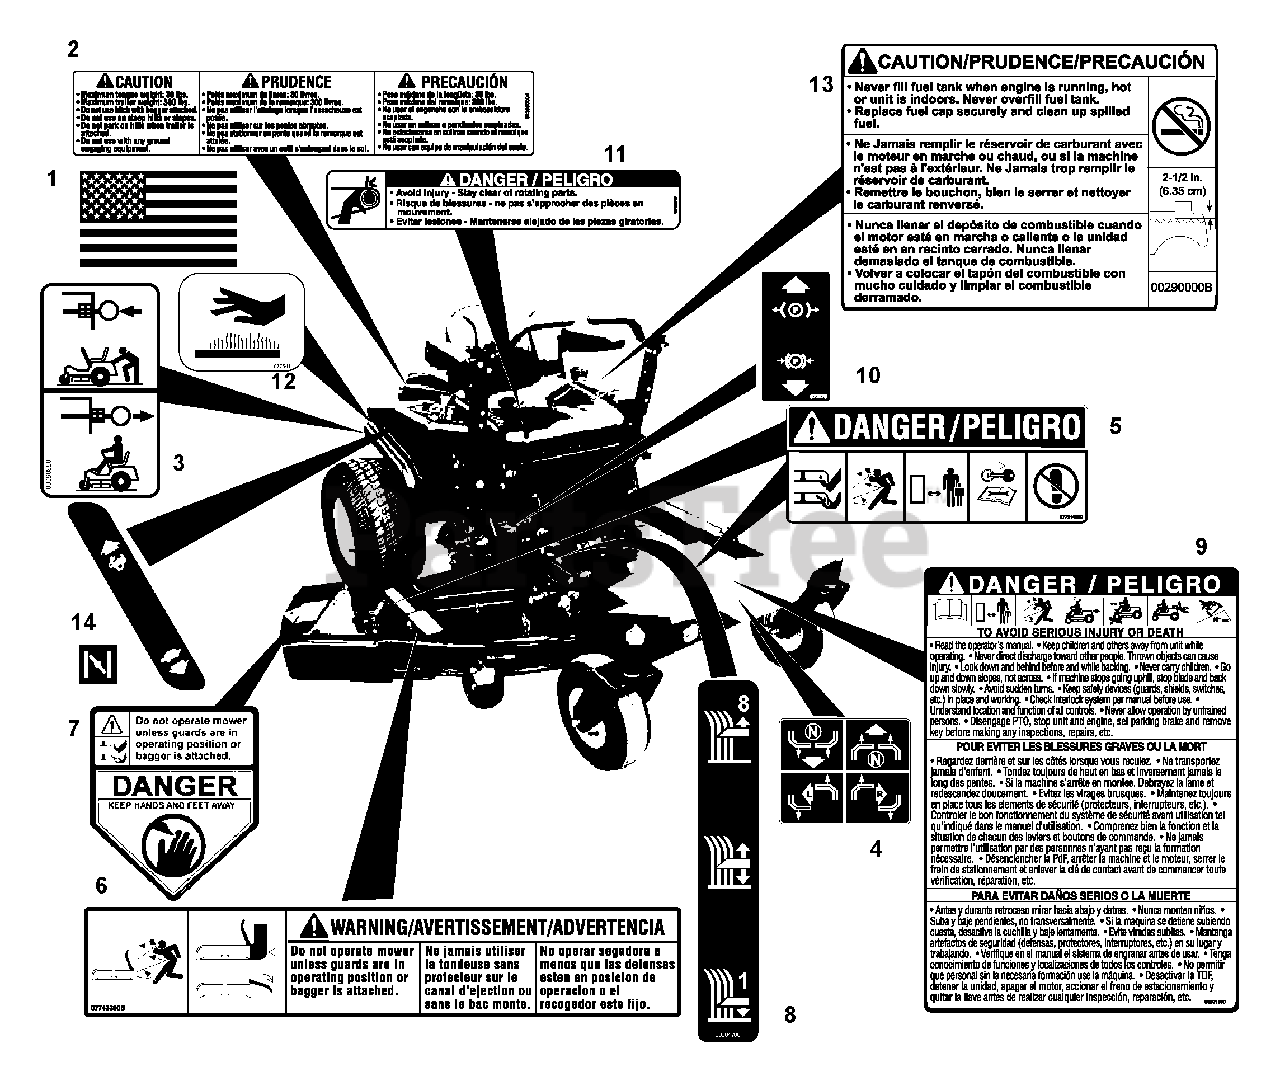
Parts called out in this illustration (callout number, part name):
1	DECAL, AMERICAN FLAG
2	DECAL, TRAILER HITCH
3	DECAL, TRANSMISSION DISCONNECT
4	DECAL, INSTRUCTIONAL-STEERING
5	DECAL, MOWER PAN DANGER
6	DECAL, WARNING
7	DECAL, CPSC DANGER
8	DECAL,CUT HEIGHT
9	DECAL, DANGER BILINGUAL
10	DECAL, PARKING BRAKE LEVER
11	DECAL- DANGER
12	DECAL, HOT SURFACE
13	DECAL,FUEL WARNING
14	DECAL, SPEED CONTROL
